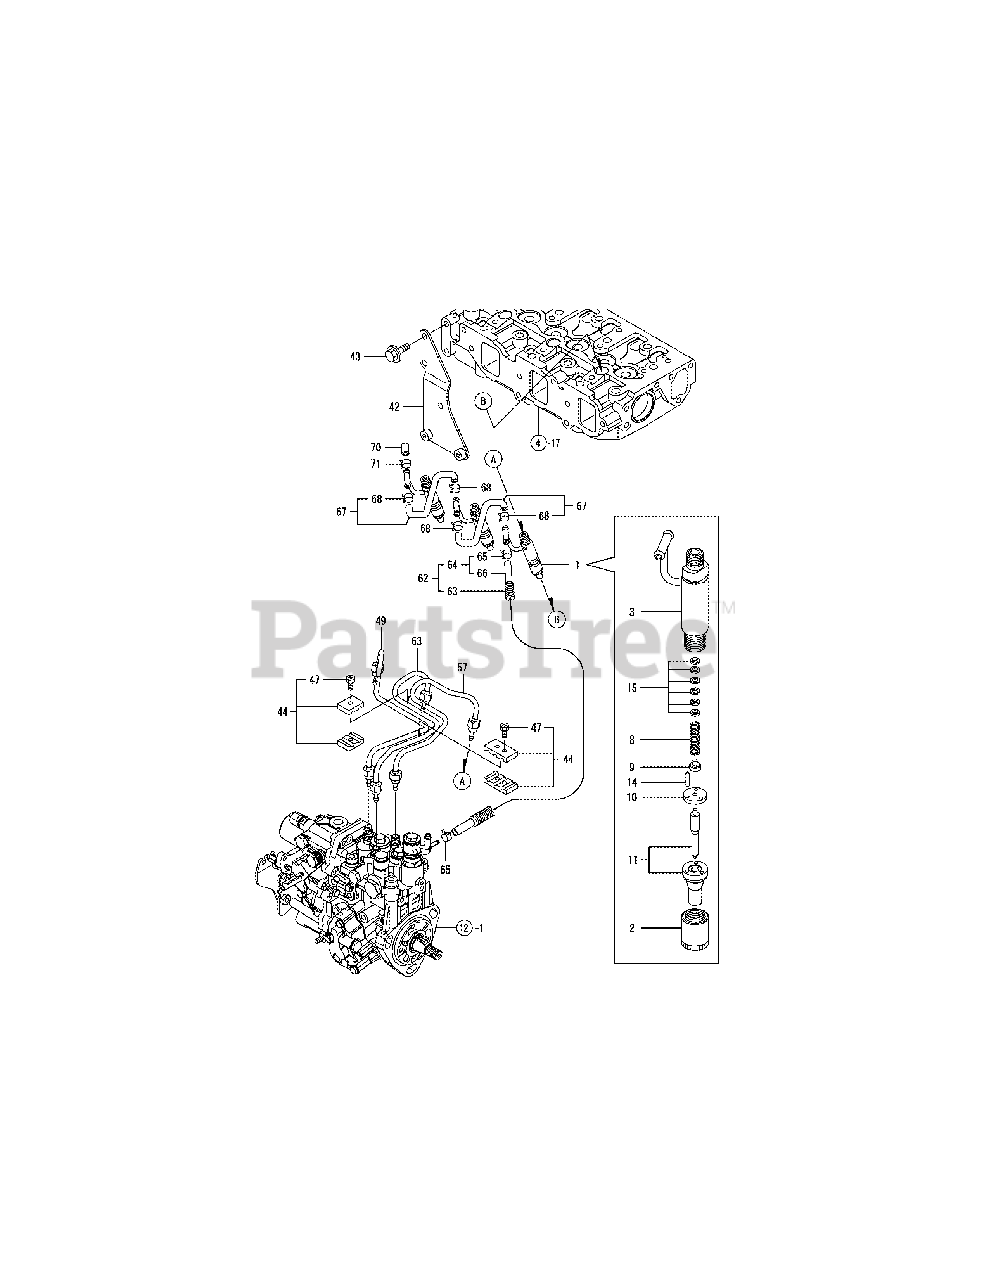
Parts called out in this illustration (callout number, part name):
1	FUEL INJECTOR(SDZ
3	HOLDER ASSY, NOZZLE
10	SPACER,VALVE STOP
15	SHIM SET
42	STAY,FEED PUMP
43	BOLT 8X 14 PLATED
44	RETAINER, INJ. PIPE
47	BOLT M4X14,HEX.SCKT.
49	PIPE ASSY, INJECTION
53	PIPE ASSY, INJECTION
57	PIPE ASSY, INJECTION
62	PIPE ASSY, RETURN
63	PROTECTOR, PIPE 10
64	PIPE ASSY, RETURN
66	PIPE, FUEL RETURN
67	PIPE,FUEL RETURN
